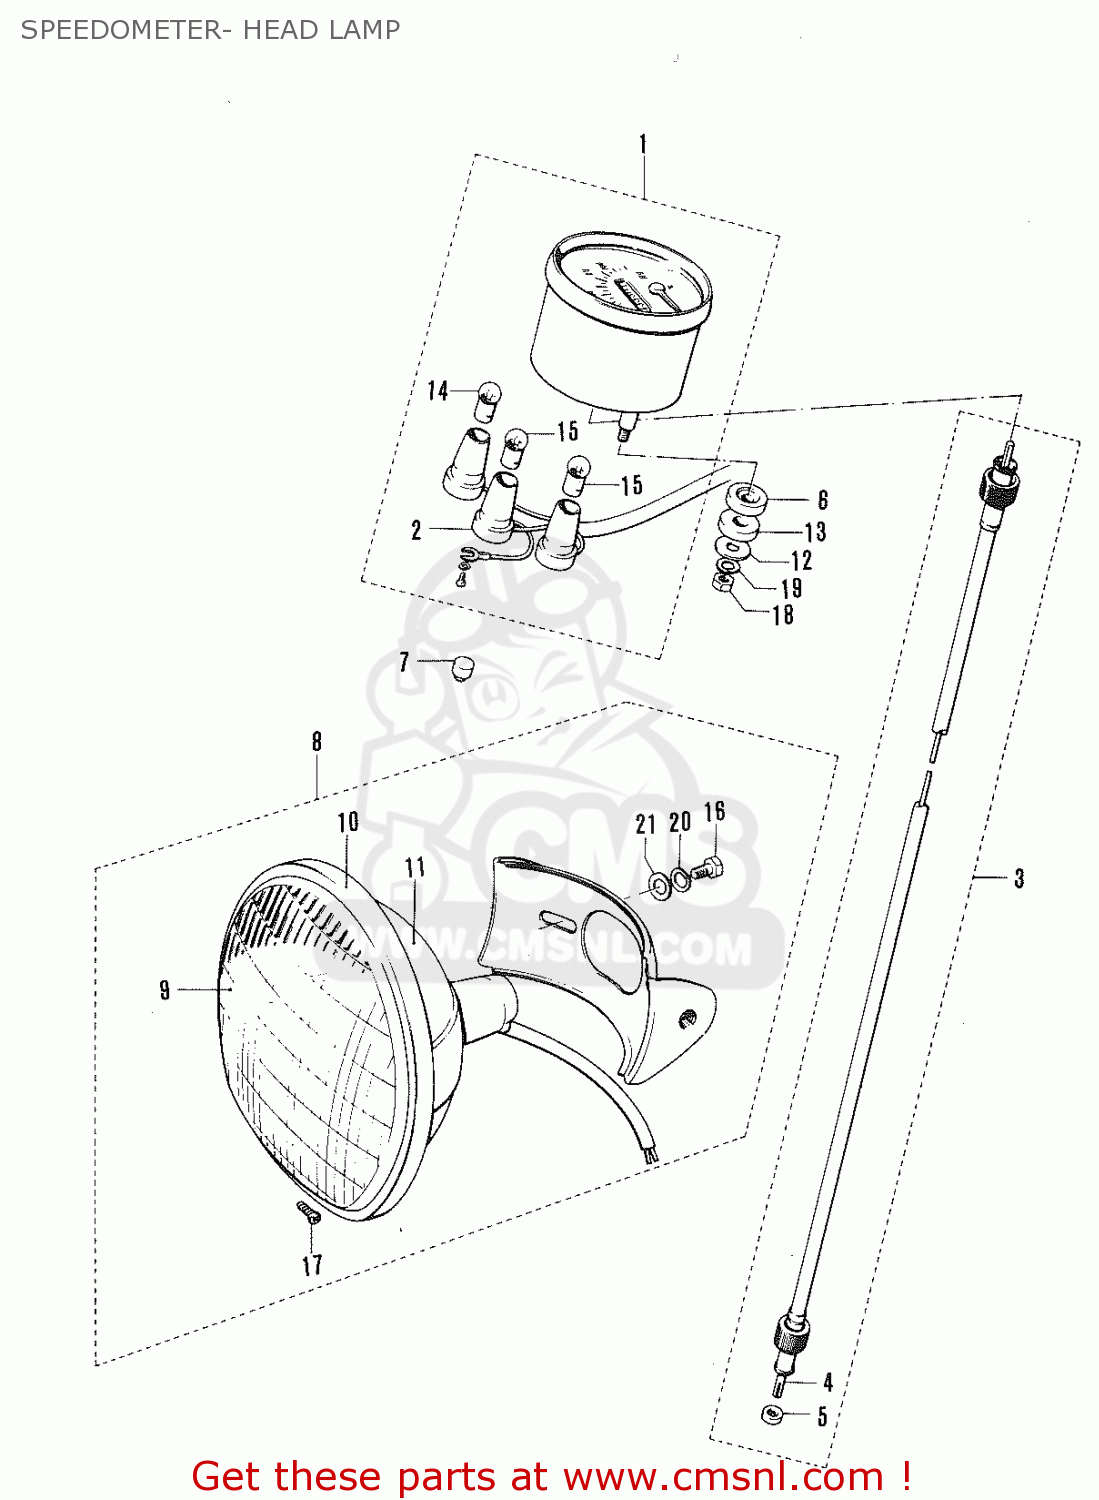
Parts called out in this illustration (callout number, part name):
1	SPEEDOMETER ASSEMBLY (MPH)
2	SPEEDOMETER SOCKET ASS'Y
3	CABLE ASSEMBLY,SPEEDOMETER
4	CABLE ASSEMBLY,SPEEDOMETER
5	SEAL,OIL METER CABLE
6	CUSHION,METER
7	CUSHION,METER
8	HEADLAMP ASSEMBLY
9	LAMP UNIT
10	RETAINER,HEADLAMP
11	STAY
12	WASHER (5.5X18X1.6)
13	CUSHION
14	BULB(6V1.7W,STANLEY,A61A)
15	BULB(6V/3W)
16	HEXAGON BOLT
17	SCREW
18	NUT
19	LOCK WASHER
20	LOCK WASHER
21	WASHER
